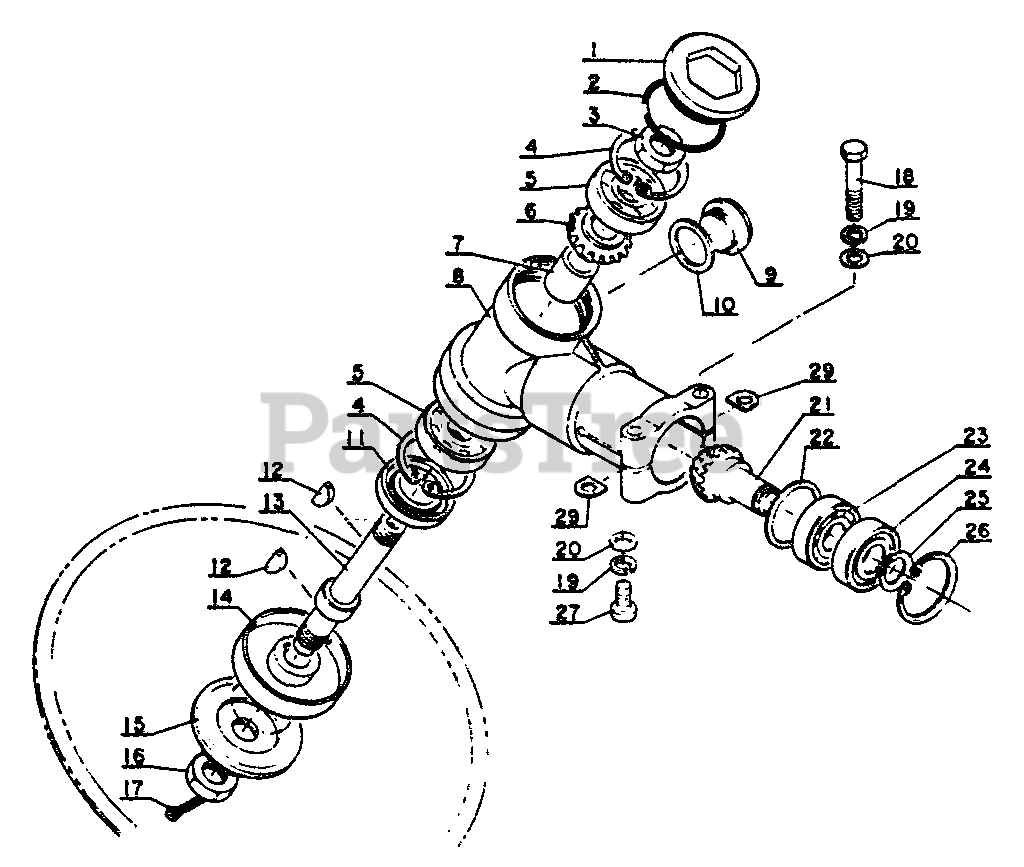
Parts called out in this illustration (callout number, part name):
1	LID, GEAR CASE
2	O-RING - 30
3	NUT - 10
4	RING, RETAINING - 30
5	BEARING, BALL - 6200
6	GEAR SET
7	SPACER
8	CASE, GEAR
9	FITTING, GREASE
10	CASE, GEAR
11	SEAL, OIL
13	DRIVESHAFT
14	ADAPTOR, BLADE - UPPER
15	ADAPTOR, BLADE - LOWER
16	NUT - 10 -- LEFT HAND
17	PIN, SPLIT - 2X22
18	BOLT - 5X30
19	LOCKWASHER - 5
20	WASHER - 5
21	GEAR SET
23	BEARING, BALL - 6001
24	BEARING, BALL - 6001
25	RING, RETAINING - 12
26	RING, RETAINING - 28
27	SCREW - 5X10
